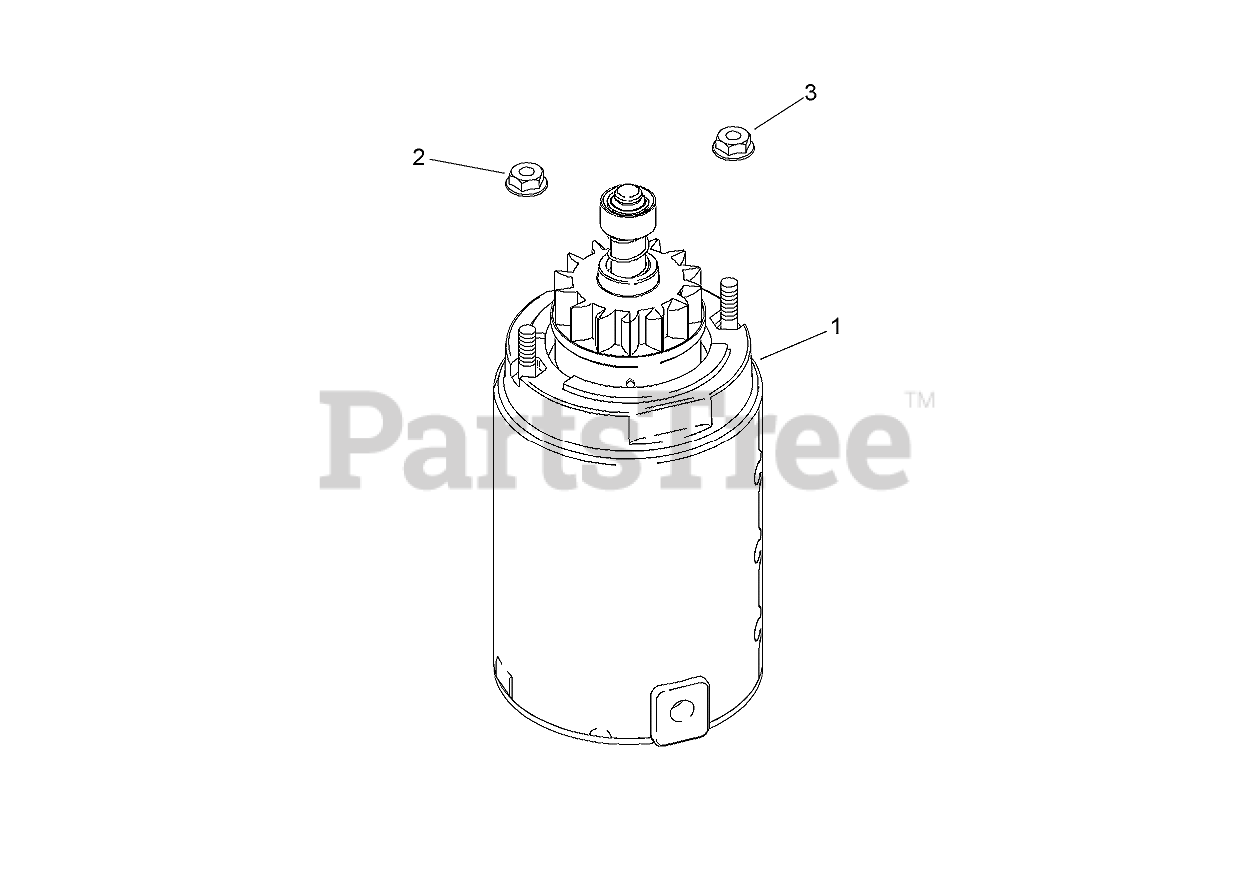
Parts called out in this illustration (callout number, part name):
1	STARTER ASM
2	Nut-Flange, Hex Serrated (10-24)
3	Nut-Flange, Hex (1/4-20)
